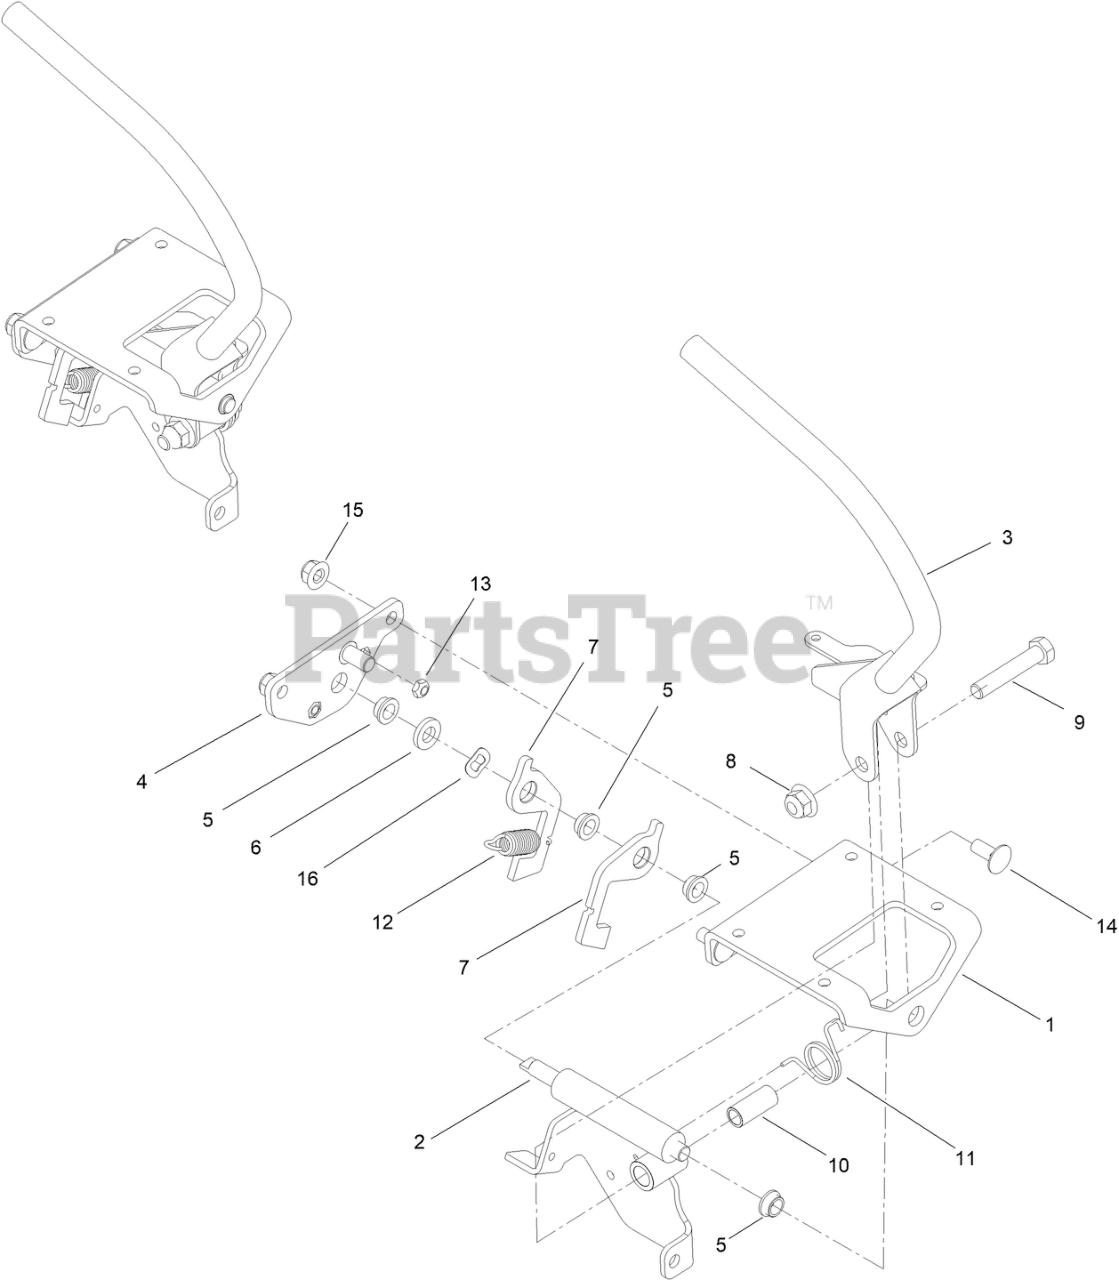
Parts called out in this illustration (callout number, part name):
1	BRACKET-CONTROL MOUNT
2	MOTION CONTROL ASM LH
3	LH LEVER ASM
4	PLATE ASM-SENSOR LH
5	BUSHING-FLANGED NYLON
6	WASHER
7	PLATE-SPRING
8	NUT-HF, NI
9	SCREW-HH
10	BEARING-SLEEVE
11	SPRING-TORSION
12	SPRING-EXTENSION
13	NUT-LOCK, NI
14	SCREW-CARR
15	NUT-HF, NI
16	WASHER-WAVE
